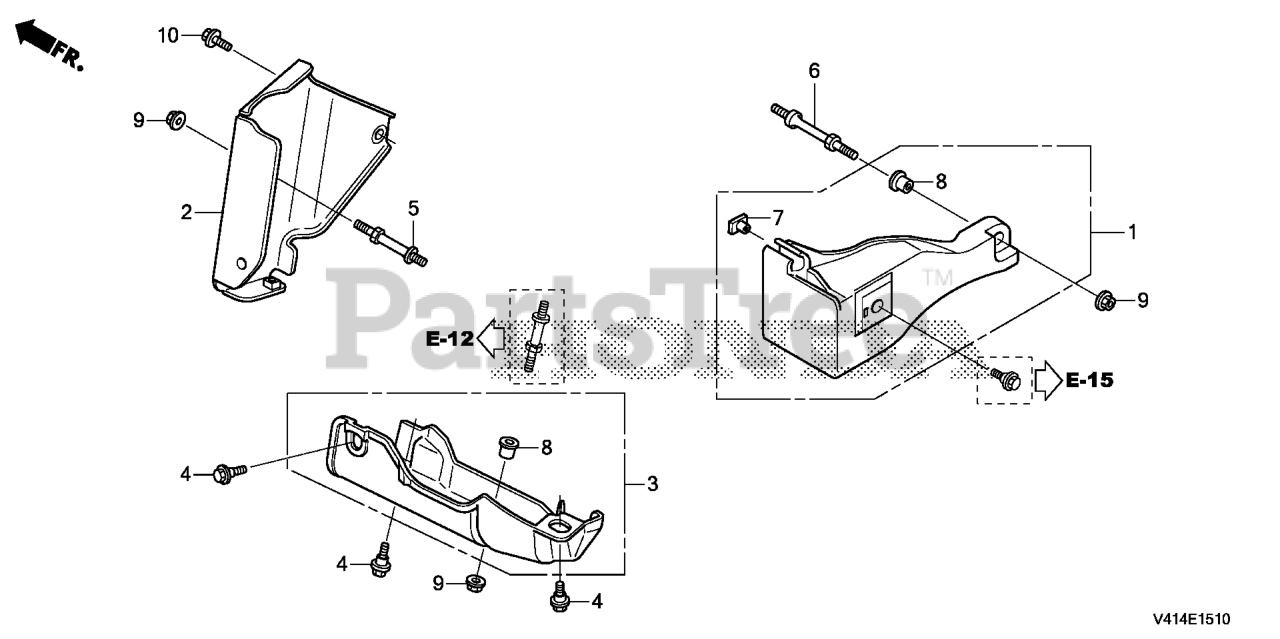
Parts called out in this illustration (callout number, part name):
1	COVER, GOVERNOR
2	SHROUD, FR.
3	GUIDE, AIR
4	BOLT, FLANGE (6MM)
5	BOLT, FR. SHROUD
6	BOLT, GOVERNOR COVER
7	NUT, SPECIAL (6X7)
8	COLLAR (6.5X6)
9	NUT, FLANGE (6MM)
10	BOLT, FLANGE (8X16) Use from Engine SN 1000016.
